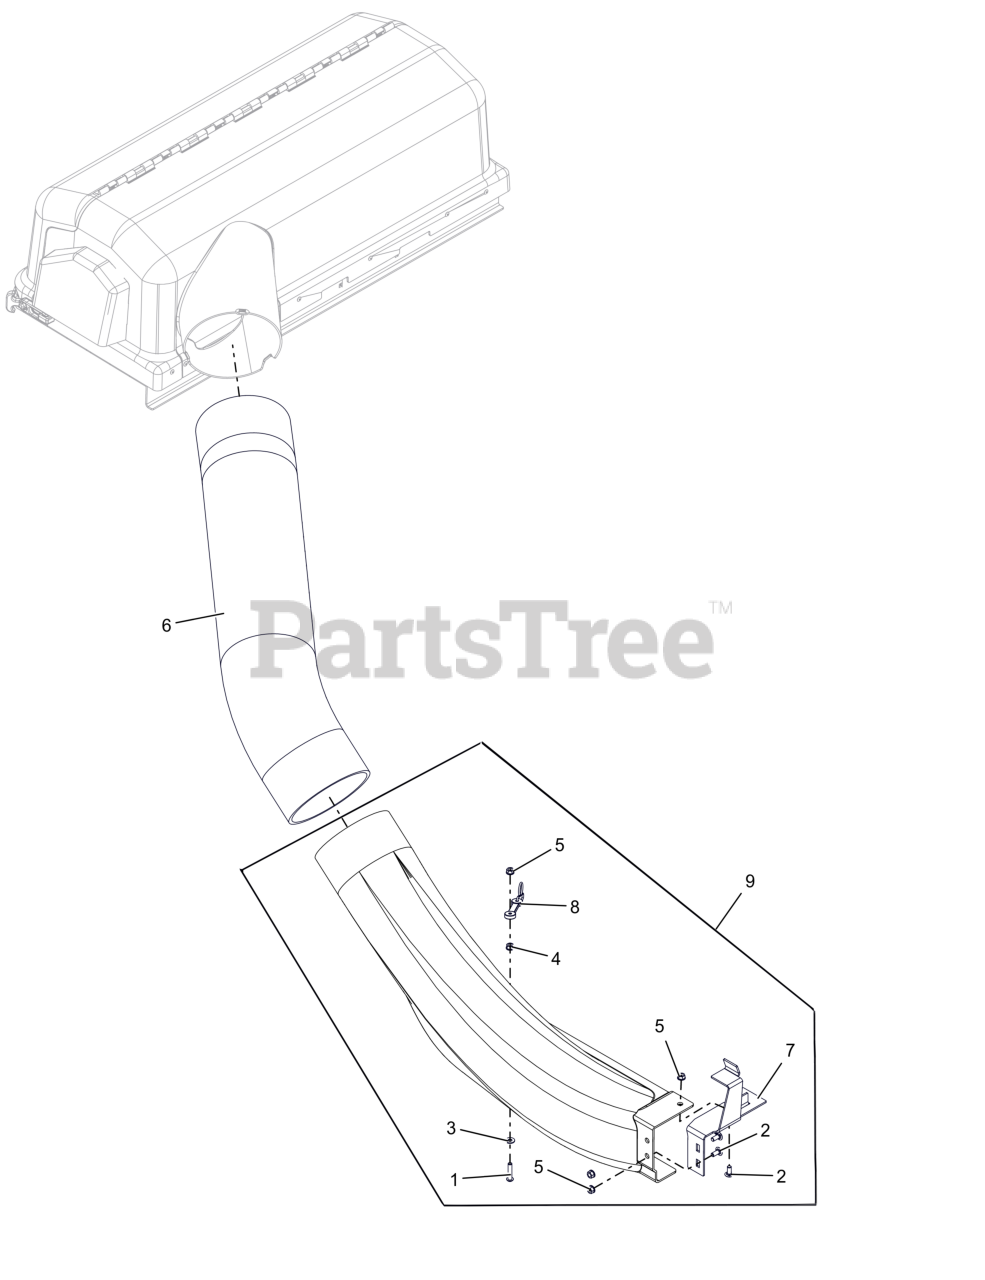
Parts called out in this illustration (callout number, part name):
1	SCR,BTNHD .31-18X1.50 ZCC
2	BLT, RHSSN.31-18X.750 G5 ZCC
3	WSHR, FLT .312X.734X.065 ZCC
4	NUT,SPNLK-FLG .31-18 G5 ZCC
5	NUT,LK-CTR-FLG .31-18 GF ZCC
6	HOSE, BAGGER 7 X 42
7	BRKT, BOOT POSITIONING (BLACK)
8	STRAP, RUBBER BOOT
9	KIT, BAGGER BOOT W/DECAL
